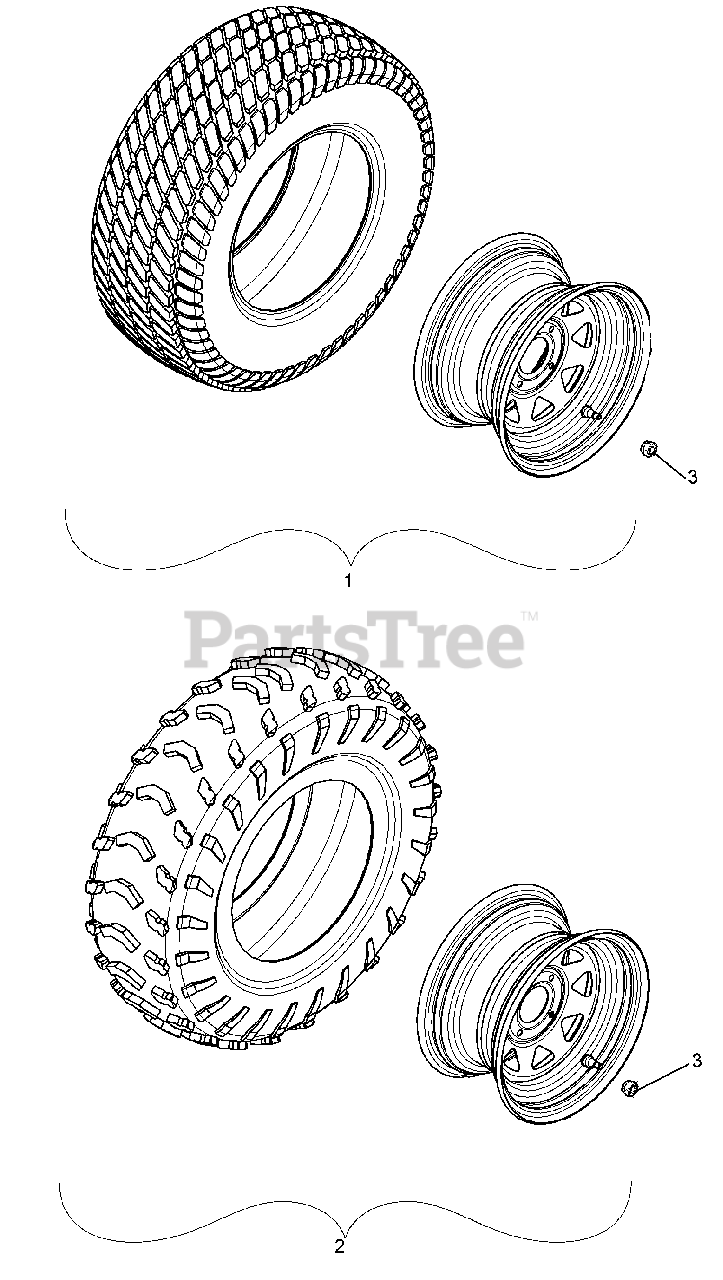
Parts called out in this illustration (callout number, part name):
1	TIRE/WHEEL ASSEMBLY TREKER TURF FRONT (996125)
2	AT TIRE/RIM, BLACK RIGHT FRONT (996123, 146, 147)
2	AT TIRE/RIM, BLACK LEFT FRONT (996123, 146, 147)
3	WHEEL NUT .500-20 YZ
